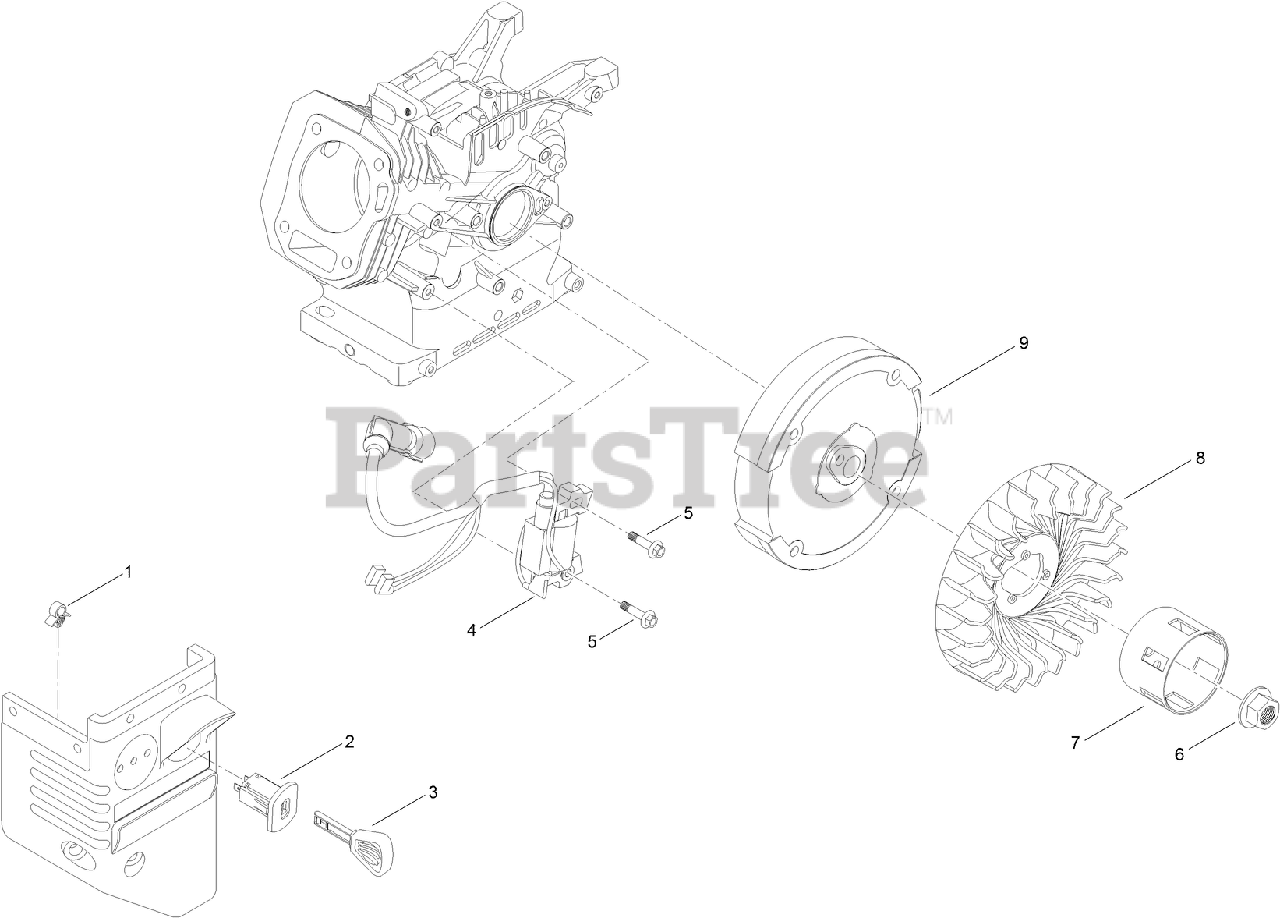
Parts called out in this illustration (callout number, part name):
2	SWITCH-KEY
4	IGNITION COIL ASM
5	SCREW-HHF
6	NUT-FLANGE
7	CUP-STARTER
9	FLYWHEEL-RECOIL
